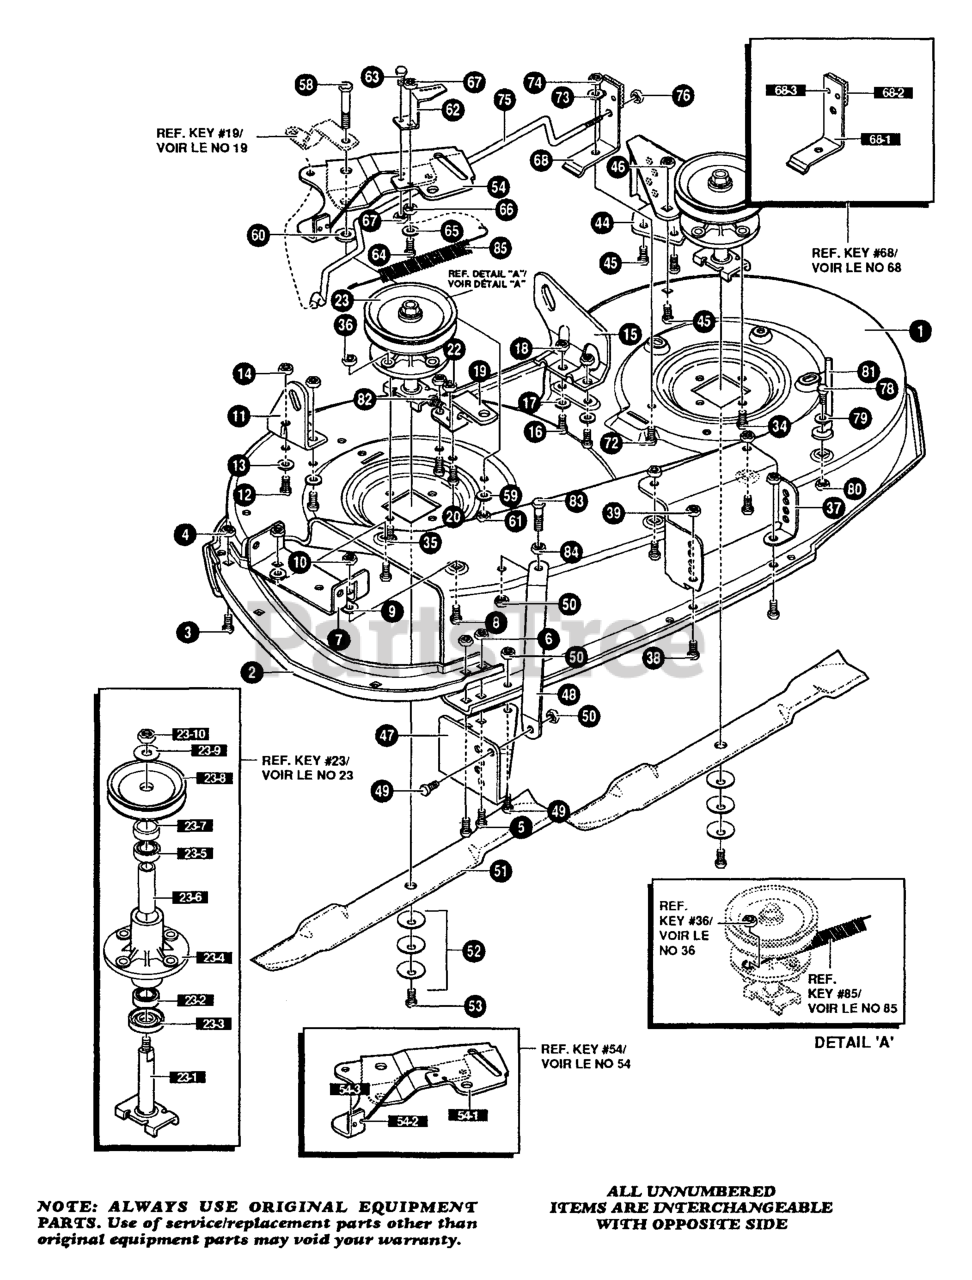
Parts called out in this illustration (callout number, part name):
1	43" DECK KIT
2	TOE GUARD
3	SCREW
5	SCREW
7	BRKT, CHUTE
8	SCREW
9	WASHER
11	BRKT, RH, REAR
12	SCREW
13	WASHER
15	BRKT, LH, REAR
16	SCREW
17	WASHER
19	BRACE, IDLER
20	SCREW
23	QUILL ASSY
23-2	BEARING, BALL
23-3	DUST SHIELD
23-4	QUILL CASTING
23-5	BEARING, BALL
23-8	PULLEY
34	SCREW
37	BRACKET FRONT
38	SCREW
44	BRKT, WHEEL, LH
45	SCREW
47	BRKT, WHEEL, RH
48	BRKT, STABILIZER
49	SCREW
51	BLADE, 43"
52	WASHER
54	IDLER ARM ASSY
54-1	ARM IDLER
54-2	RIVET
54-3	BRAKE PAD
59	WASHER
62	BRKT, EXT IDLER
63	SCREW
68	BLADE BRAKE ASSY
68-2	BRAKE ARM
68-3	BRAKE PAD
72	SCREW
73	WASHER
75	ROD, BRAKE
79	WASHER
81	BELT GUIDE
85	SPRING
